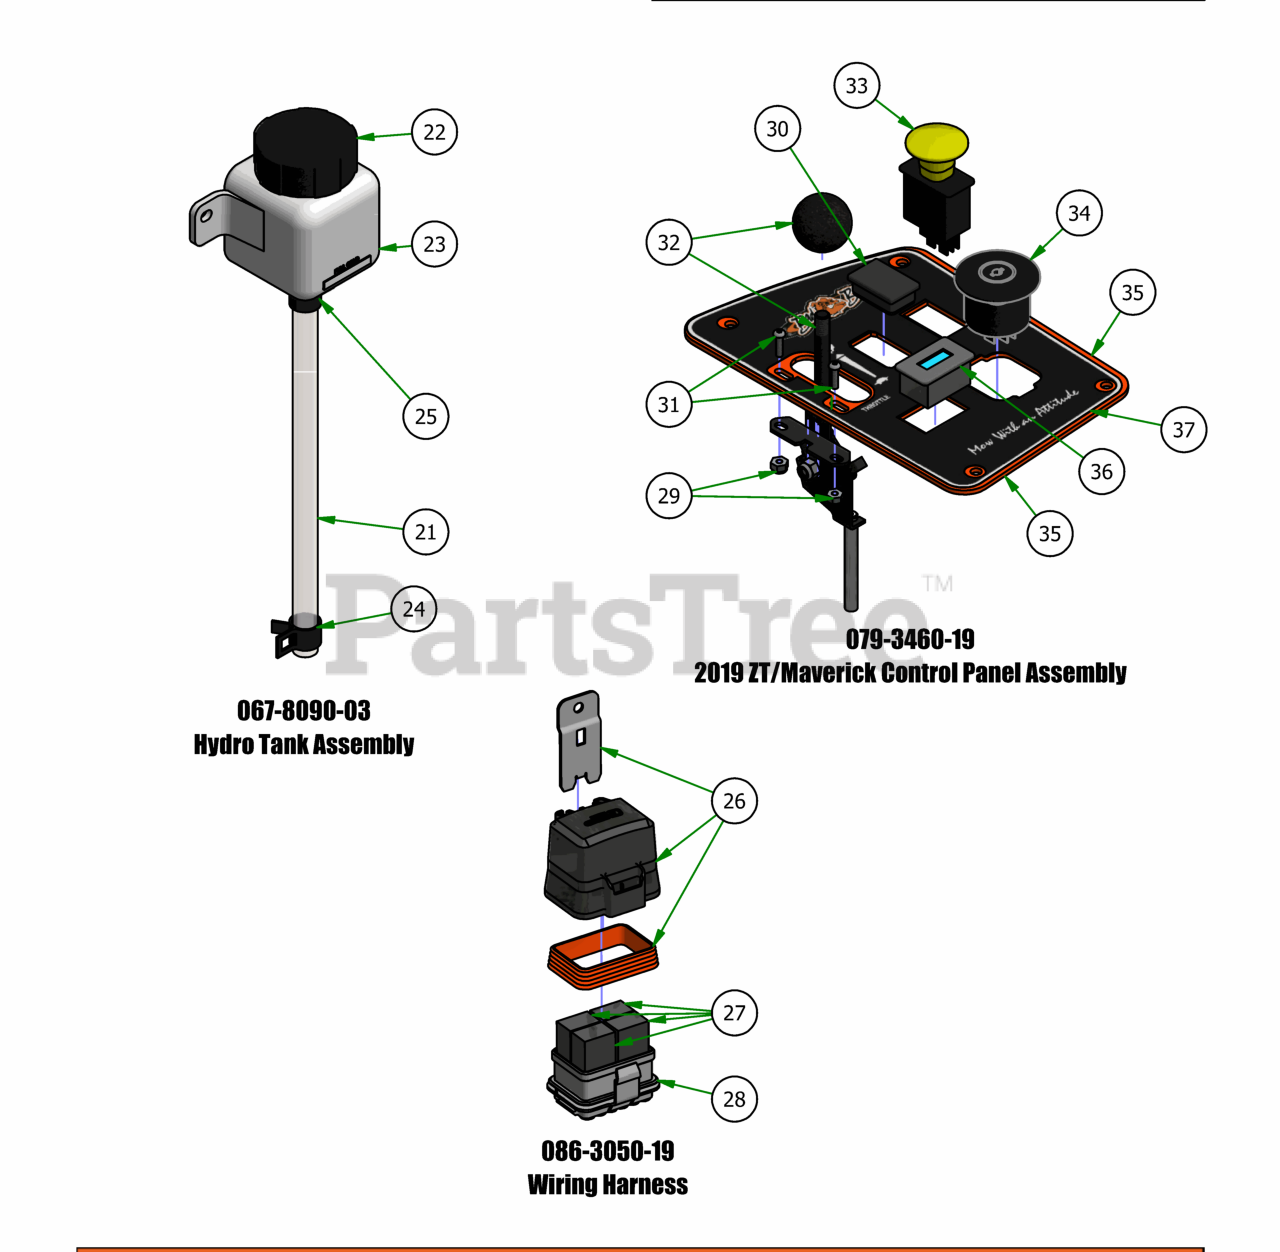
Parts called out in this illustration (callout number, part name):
21	ZT/Maverick Hydro Tank Hose
22	Hydraulic Tank Cap
23	350ml Expansion Tank
24	3/8" Hose Clamp
25	1/2 Hose Clamp
26	Relay Block Cover Replacement Kit
28	Wiring Harness
29	10-24 Nylon Insert Locknut Zinc Orange Nylon
30	Light Plug
31	10-24 X 5/8 BS Button Head Bolt
32	Throttle Lever Assembly
33	PTO Engager
34	Ignition Switch
35	Control Panel
36	Tachometer
37	2018 MZ/Magnum/ZT/Maverick Control Panel Decal
